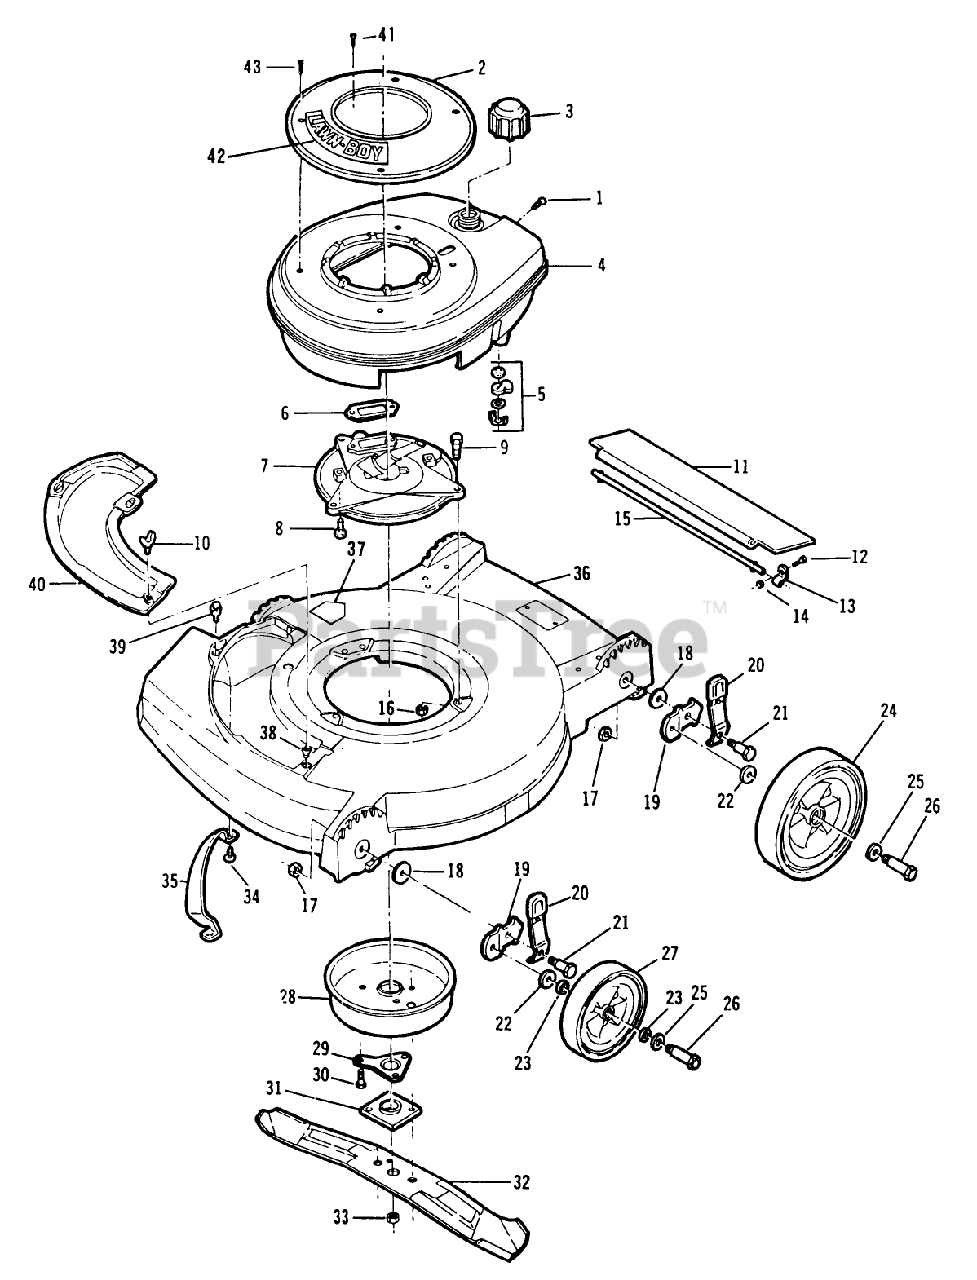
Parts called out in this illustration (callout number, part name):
1	SCREW S
3	FUEL CAP & INSERT
5	SHUT OFF VALVE KIT
7	PLATE F
8	SCREW V
9	SCREW-HH
10	WING SCREW LAWRE
13	CLAMP ROD KMC
14	LOCKNUT E
15	ROD T/SHIELD ADV WIRE
16	NUT-LOCK F
17	LOCKNUT
18	WASHER
20	SPRING ARM ASM
21	BOLT
22	WASHER WROUGHT
23	Felt Washer
24	WHEEL&TIRE 8" TRI
25	SPACER
26	BOLT WHEEL
28	MUFFLER COVER F
29	SUPPORT F
30	SCREW
31	PLATE AND COLLAR ASM
33	NUT-BLADE
35	TOE BAR 19"
41	SCREW SEMS SM
43	SCREW - SELF TAPPING
